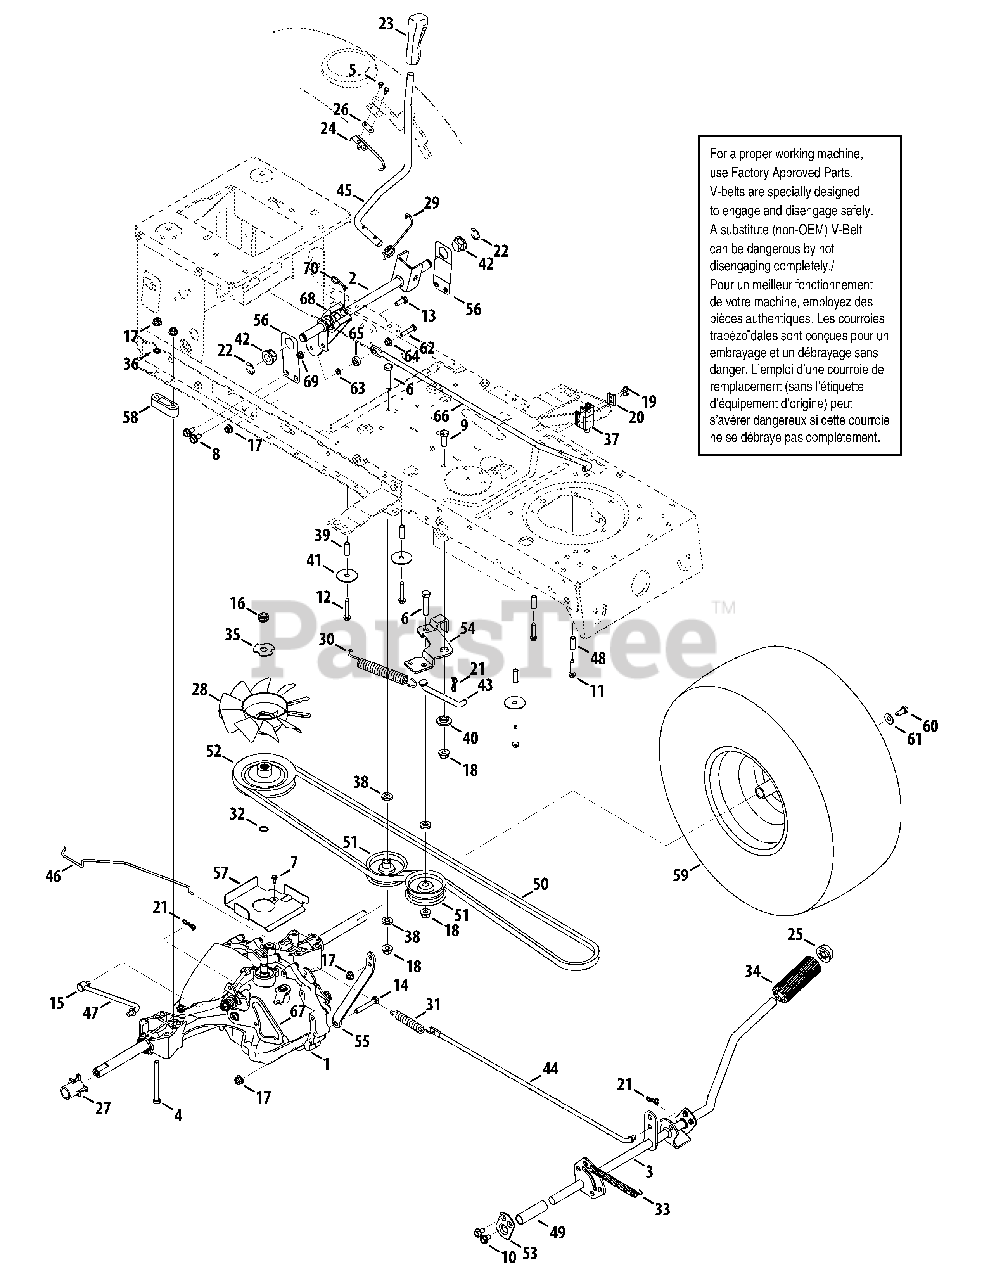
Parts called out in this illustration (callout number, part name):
1	Transmission Ass’y
2	Hydro Hand Control Ass’y
5	Hex Wash HD AB S-Tapp Screw #8-.50
6	Hex Screw 3/8-16 x 1.75
7	Screw #10-16 x .50
8	S-Tapp Screw 5/16-18 x .75
9	Hex Screw 3/8-16 x 1.0
10	Hex Screw 5/16-18 x 0.625
11	Hex Bolt 1/4-20 x 1.25
12	Screw 1/4-20 x 1.75
13	Hex Bolt 5/16-18 x .75" Lg. Gr. 5
14	Screw, #10-24 x .75
16	Jam L-Nut 1/2-20
17	Flange Locknut 5/16-18 Gr. F, Nylon
18	Flange Locknut 3/8-16 Gr. F, Nylon
20	Switch Plate
21	Bow Tie Cotter Pin
22	"E" Ring .625 Dia.
24	Hydro Spring Switch
25	Push Cap 5/8" Dia Rod
26	Insulator Nut Plate
27	Sleeve, .765 x 2.11" Lg.
29	Torsion Spring
30	Ext. Spring .75 Dia. x 6.02
31	Ext. Spring .59 OD x 4.00 Lg.
33	Extension Spring .50 dia. x 6.37
34	Foot Pad
35	LockwasherTrans Hydro
36	Lockwasher 5/16 ID
37	Interlock Switch
38	Flat Washer .407 x .812 x .135 HT
39	Spacer .260 x .372 x 1.420
40	Control Speed Se lec tor Rod
41	Flat Washer .350 x 1.59 x .062
42	Hex Flange Bearing .630 ID
43	Declutching Rod
44	Brake Rod
45	Hydro Control Handle
46	Hydro Bypas Rod
47	Hydro Control Rod
48	Spacer, .260 x .375 x 1.030" Lg.
49	Spacer, .640 x .76 x 2.6" Lg.
50	V-Belt 4L SEC x 84.17 Lg
51	Flat Idler Pulley 2.75 OD
56	Handle Bracket
57	Belt Support Bracket
58	Spacer, T-Axle, 46" only
60	Hex L-Screw 5/16-24 x 0.75 Gr. 5
61	Cup. Wash. .345 ID x .88 OD x .060
62	Hex Screw 1/4-20 x 1.25
63	Flt Washer .281 x .50 x .063
64	Screw, 1/4-20 x .5
65	Ball Bearing .25 x .6875 x .25
66	Hydro Rod, RTN
69	Hex L-Flg. Nut 1/4-20 Gr. F, Nylon
70	Click Pin, .092 x 1.64" Lg.
